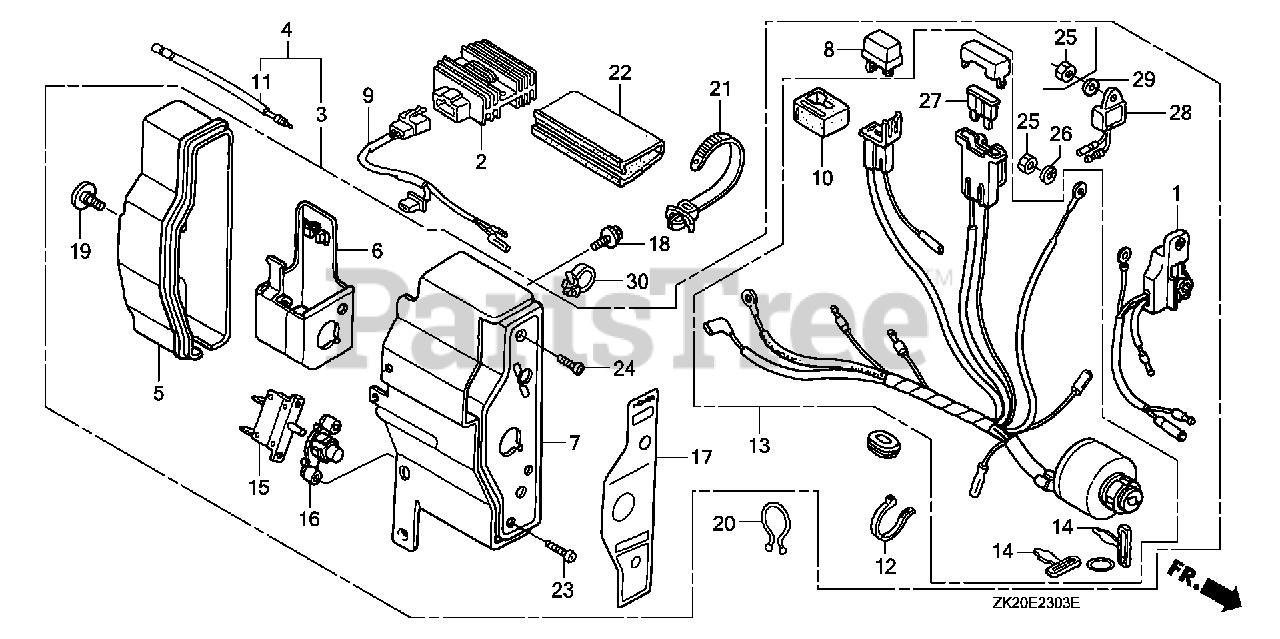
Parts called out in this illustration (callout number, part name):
1	ALERT UNIT, OIL (SEL) (NOT AVAILABLE)
3	BOX ASSY., CONTROL (3A) *R8* (EXP-ALERT) (BRIGHT RED) (NOT AVAILABLE)
4	BOX ASSY., CONTROL (3A) *R280* (EXP-ALERT) (POWER RED)
5	CASE, CONTROL
6	BRACKET, CASE MOUNTING
7	PANEL, CONTROL *R280* (POWER RED)
8	RECTIFIER ASSY., SILICON (SHINDENGEN)
10	SUSPENSION, CONNECTOR
11	SUB-WIRE HARNESS
13	SWITCH ASSY., COMBINATION (3A-CHARGE)
14	KEY (HONDALOCK)
15	PROTECTOR, CIRCUIT (3.5A)
16	LENS ASSY., PROTECTOR
17	MARK, CONTROL BOX (EXP)
17	PANEL, CONTROL BOX (EXTERNAL-ALERT) (NOT AVAILABLE)
18	BOLT, FLANGE (6X12) (CT200)
19	SCREW, SPECIAL (6X12)
20	CLIP, PURSE LOCK
21	STRAP, CABLE (118MM) (BLACK)
22	TUBE, FASTENER (30MM)
23	SCREW, PAN (3X12)
24	SCREW, PAN (4X12)
25	NUT, HEX. (4MM)
26	WASHER, SPRING (4MM)
27	FUSE, BLADE (15A)
30	HOLDER, STOP SWITCH WIRE
